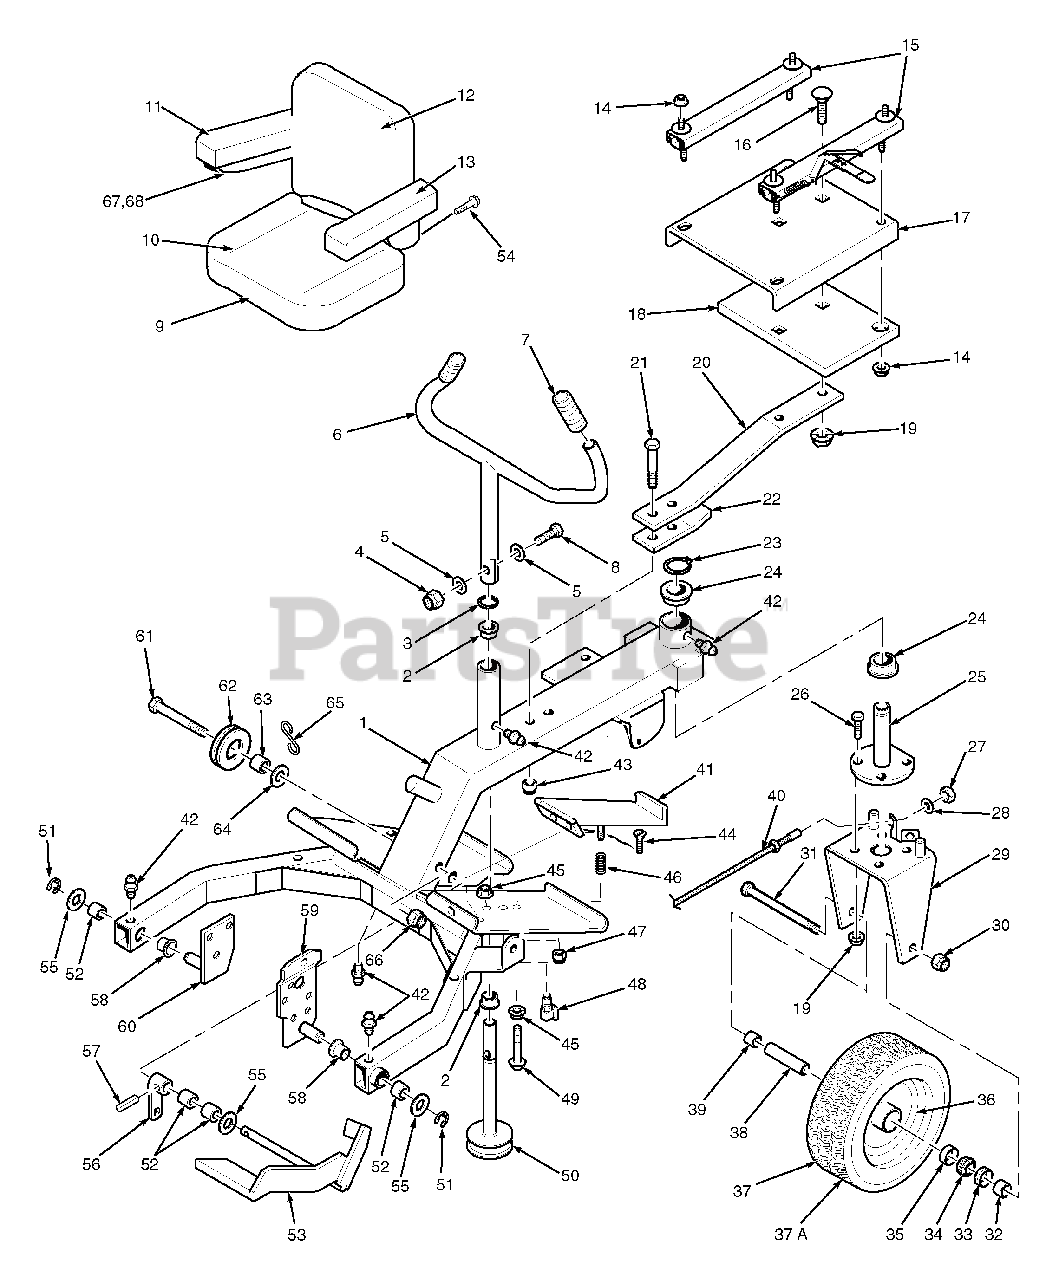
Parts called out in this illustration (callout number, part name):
1	Steering Frame
2	Bronze Bushing, 7/8 ID x 1.0 Flanged
3	Retaining Ring, 7/8 external
4	Hex Nut, Elastic Stop 5/16-18
5	Flat Washer, 5/16 (3/8 x 7/8 x 13 ga.)
6	Steering Handle
7	Grip
8	Bolt, Hex Hd., 5/16-18 x 1-3/4"
9	Seat Assy.
10	Cushion Assembly
11	Arm Pad - R.H.
12	Seat Back Cushion
13	Arm Pad - L.H.
14	Serr. Fl. HH. Nut, 5/16-18
15	Seat Adjuster Track
16	Bolt, RDHD Carr. 3/8-16 x 1-1/2 (52" & 61")
17	Seat Plate
18	Ballast, Seat Mount (72" cutter deck only)
19	Serr Fl. Hex Nut, 3/8-16
20	Seat Spring
21	Bolt, Hex Hd., 7-16-14 x 3-1/2"
22	Reinforcement, Seat Spring
23	Retaining Ring, 1-1/8" external
24	Bushing, Oilite - 1-1/8 ID x 1.0 Flanged
25	Rear Wheel Pivot
26	Bolt, Hex Hd., 3/8-16 x 1-1/4"
28	Lock Washer, 3/8 Internal Tooth
29	Rear Wheel Yoke
30	Hex Elastic Stop Nut, 5/8-11
31	Bolt, Hex Hd. 5/8-11 x 9"
32	Spacer, Rear Wheel, short
33	Seal, Grease
34	Bearing Cone
35	Bearing Cup
36	Rim Only
37	Rear Wheel Assy.
37A	Tire Only
38	Sleeve, Rear Wheel
39	Spacer, Rear Wheel
40	Cable, Steering
41	Pedal, Foot Safety Switch
42	Grease Fitting
43	Hex Elastic Stop Nut, 7/16-14
44	Screw, Phillips flat hd #10-32 x 3/4"
45	Serr. Fl. Hex Nut, 1/4-20
46	Spring, Foot Safety Switch
47	Hex Nut, Elastic Stop Lock, 1/4-20
48	Switch, Foot Safety
49	Bolt, Hex Hd., 1/4-20 x 1-3/4"
50	Steering Shaft
51	Retaining Ring 3/4 Ext. "E"
52	Bushing, Oilite - 3/4 ID x 1.0
53	Foot Pedal
54	Screw w/washer, 1/4-20 x .75"
55	Flat Washer, 3/4 x 1-1/4 x 16 Ga.
56	Foot Pedal Arm
57	Pin, Drive Lock 3/16 x 1-1/4"
58	Bushing, Oilite - 3/4 x .50 Flanged
59	Sulky Mtg. Brkt. L.H.
60	Sulky Mtg. Brkt. R.H.
61	Bolt, Hex Hd., 1/2-13 x 5-1/2"
62	Pulley, Winch Cable
63	Bushing, Oillube - 1/2 ID x .56
64	Flat Washer, 1/2 (.562 x 1.375 x .109)
65	Retainer, Winch Cable
66	Hex Elastic Stop Nut, 1/2-13
67	Arm Rest Bracket, Left Hand
68	Arm Rest Bracket, Right Hand
